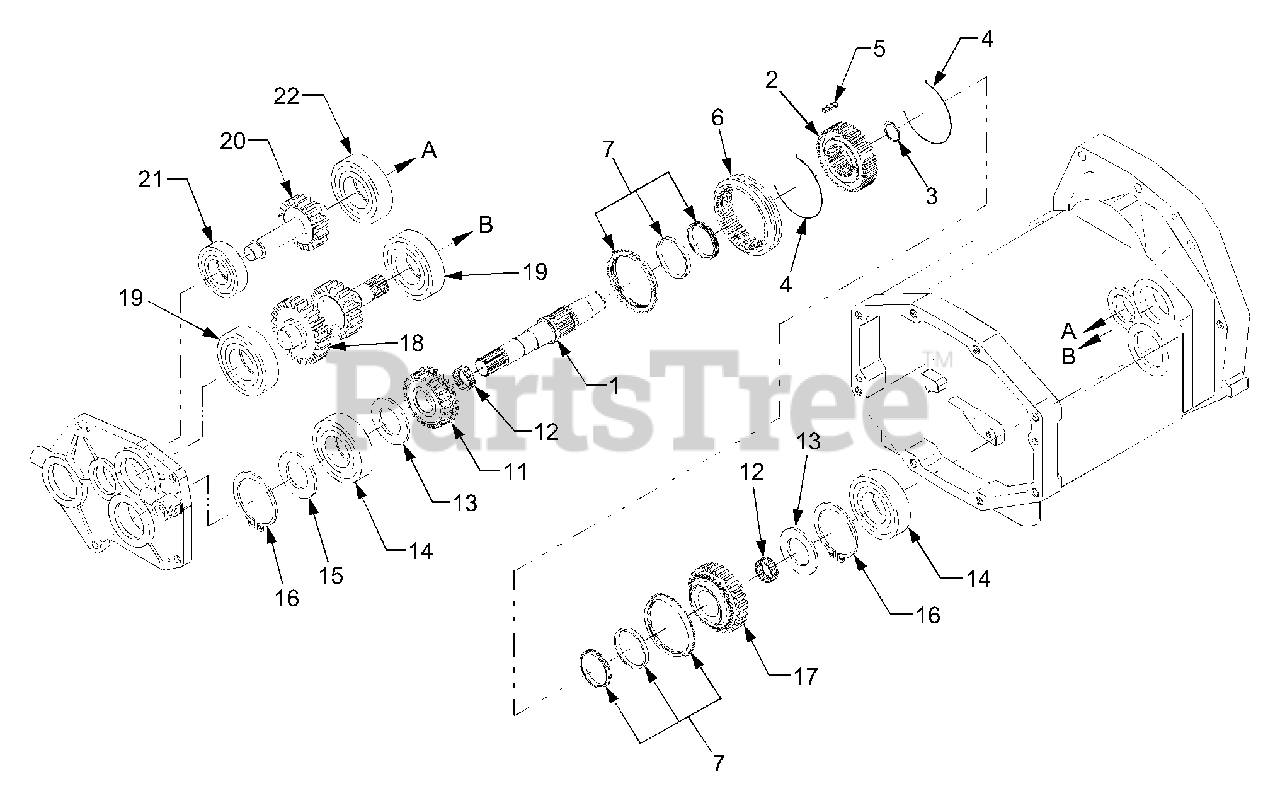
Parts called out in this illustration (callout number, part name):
1	Shaft, Shuttle
5	Key, Synchronize
7	Synchronize Ass'y
12	Bearing, Needle
13	Collar, Thrust
14	Bearing, Ball
18	Shaft, 23-21 Gear
19	Bearing, Ball
20	Shaft, 18 Gear
21	Bearing, Ball
22	Bearing, Ball
